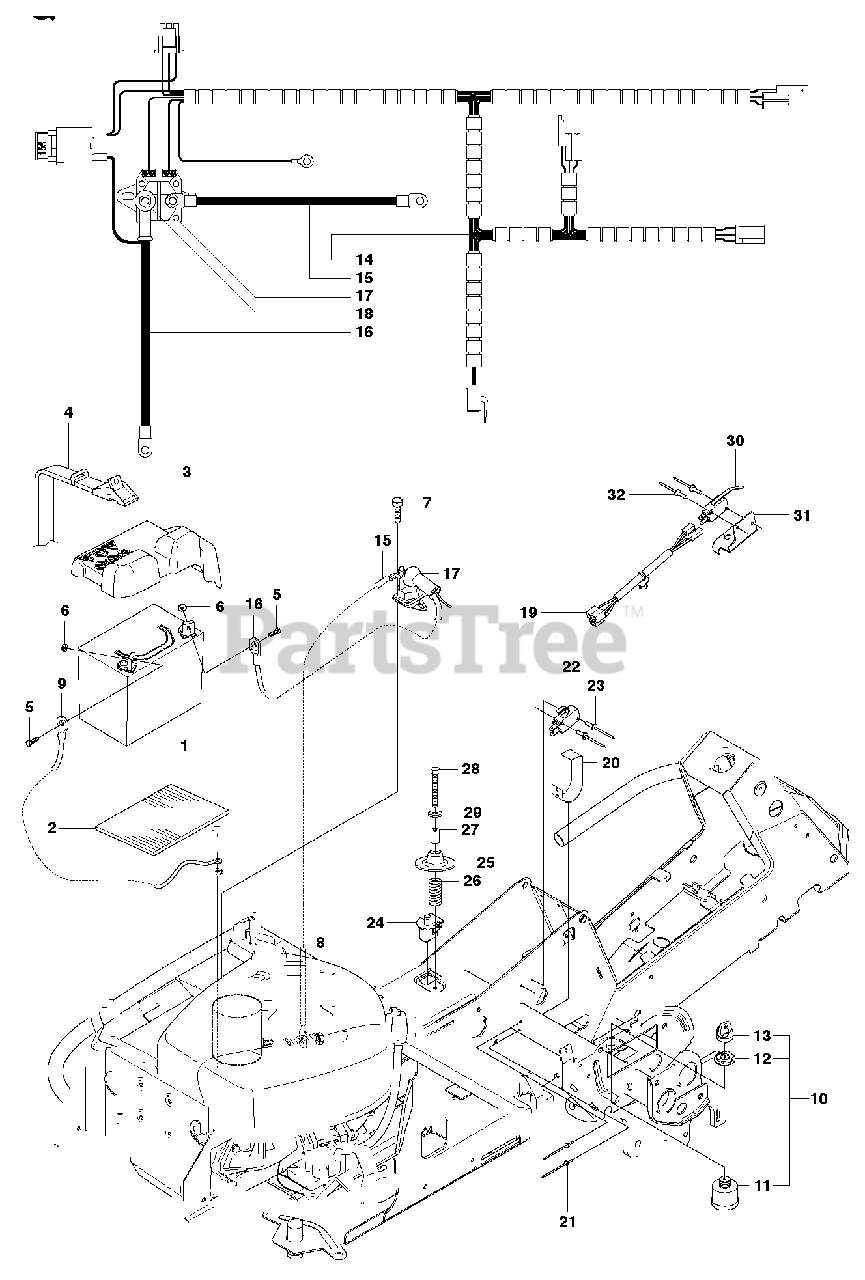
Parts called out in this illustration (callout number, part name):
5	SCREW EHHM
10	IGNITION SWITCH
11	IGNITION SWITCH
12	NUT
13	IGNITION KEY
19	WIRING
27	SPACER TUBE
28	SCREW
29	WASHER BRB 8.4X17
30	MICRO SWITCH
